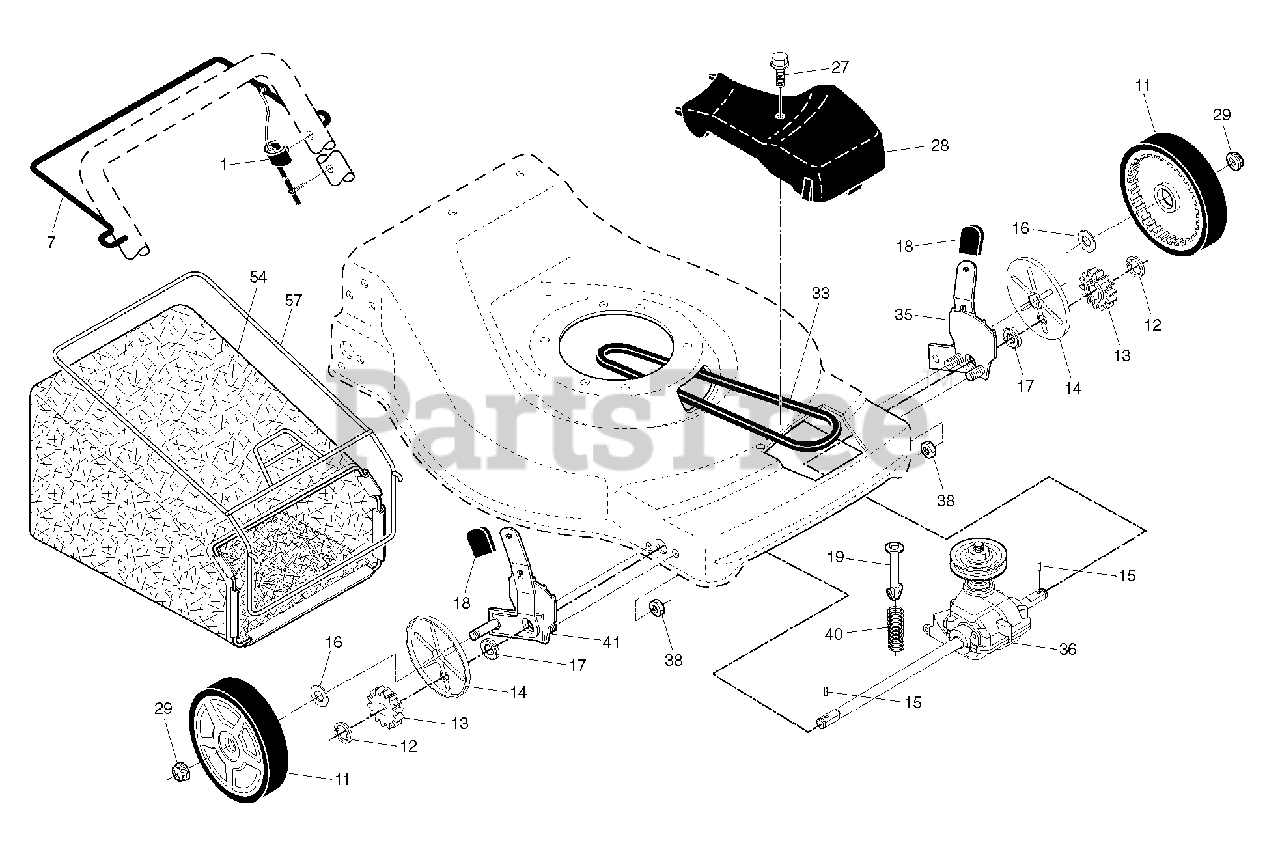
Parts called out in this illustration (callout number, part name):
1	CONTROL.DRIVE.S/SPEED.FWGD
7	BAIL.DRIVE.S/S.ROUND.MARI.21
11	RP.WHEEL.8X1.75.5SPK.RAD3.BLCK
12	E-RING 7/16 RE
13	PINION.14.TEETH.FGD
14	COVER.DUST.WHEEL
15	PAWL, DRIVE
16	WASHER FLUT
17	BEARING.ASM.
18	KNOB.ERGO.DLX.PLAS.MARI.MULTI
19	SPRING RETAINER
27	SCREW, HEX HD TAPPING #10-24 1
28	Drive Cover, Torus B&S Black
29	NUT.HEX.FLANGE.3/8-16.LOCKNUT
33	BELT THERM .32
35	KIT ADJUSTER ASM.438151.
36	TRANSMISSION.22.FGD/W/PULLEY
38	LOCKNUT.NYLOC.1/4-20
40	SPRING.EXTENSION
41	KIT ADJUSTER ASM.438148
57	Grass Bag Frame, 22" EZ Empty SC
